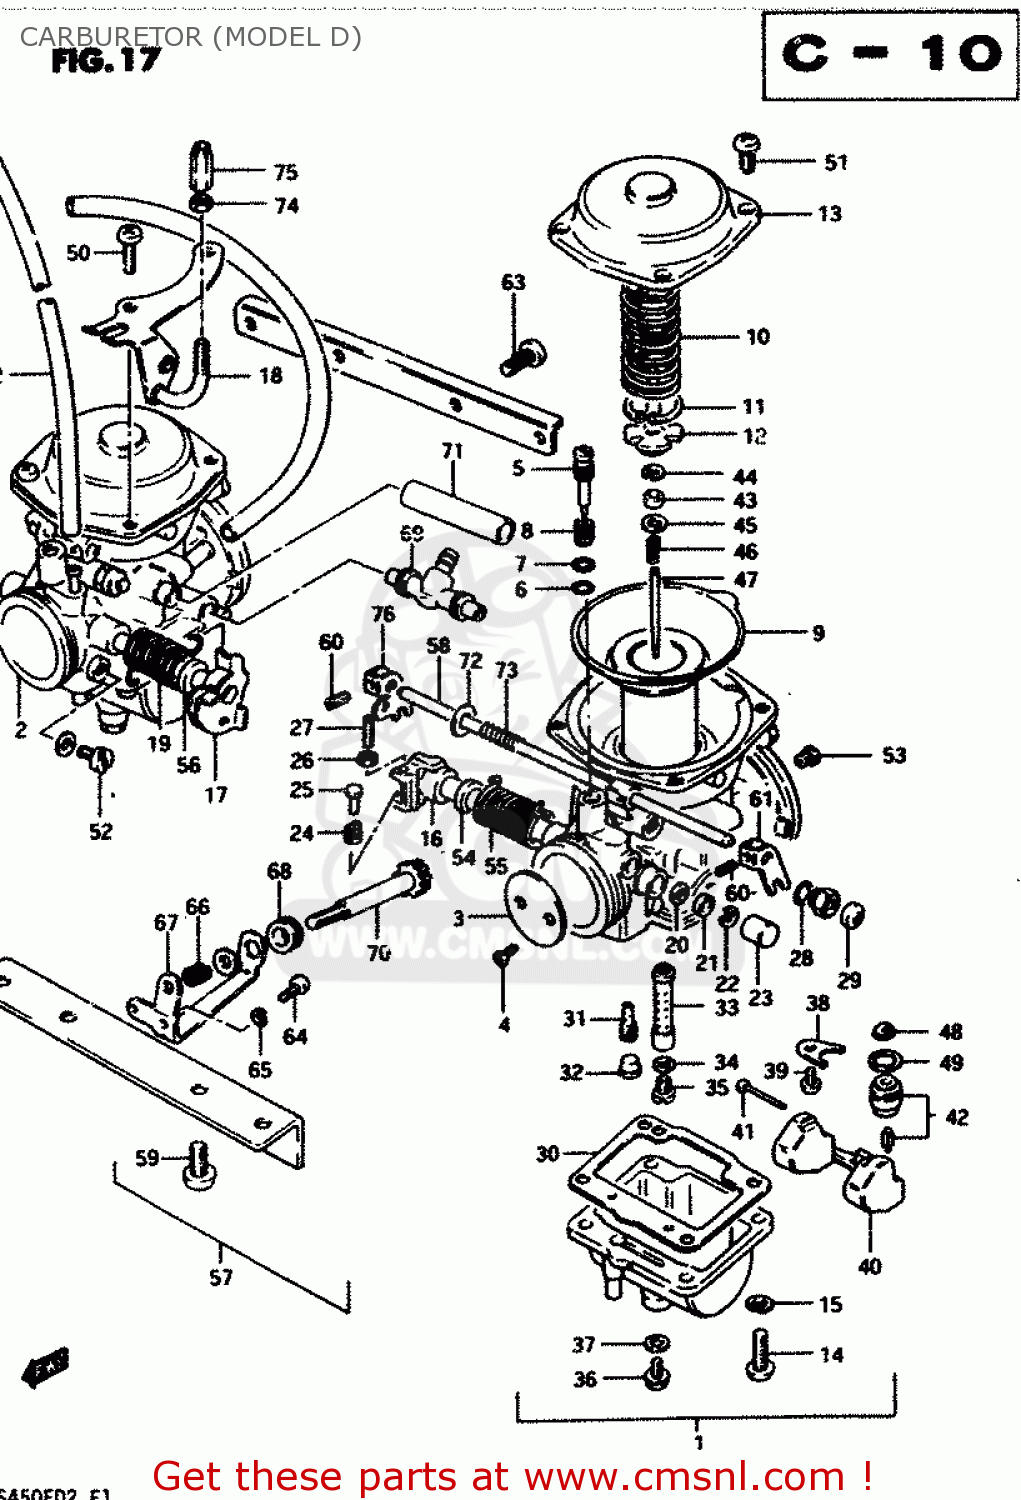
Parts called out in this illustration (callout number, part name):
1	CARBURETOR ASSY, LH
2	CARBURETOR ASSY, RH
3	VALVE, THROTTLE
4	SCREW
5	SCREW,PILOT AIR
6	O-RING
7	GASKET
8	SPRING
9	DIAPHRAGM ASSY
10	SPRING
11	E RING
12	HOLDER,GUIDE
13	COVER
14	SCREW
15	LOCK WASHER
16	SHAFT ASSEMBLY
17	SHAFT,THROTTLE
18	BRACKET,THROTTLE CABLE
19	SPRING
20	SEAL
21	GASKET,THROTTLE SHAFT (NAS)
22	E RING
23	CAP
24	SPRING,THROTTLE SCREW
25	PIN,THROTTLE LEVER
26	NUT
27	SCREW
28	O RING
29	CAP,STARTER VALVE
30	GASKET,FLOAT CHAMBER (NAS)
31	JET,PILOT(45)
32	PLUG,NEEDLE JET
33	JET,NEEDLE(R-0)
34	WASHER,NEEDLE NOZZLE
35	JET
36	PLUG,DRAIN
37	GASKET (NAS)
38	PLATE,NEEDLE VALVE FITING
39	SCREW 4X6
40	FLOAT
41	PIN,FLOAT
42	VALVE ASSEMBLY,NEEDLE
43	RING
44	CLIP
45	WASHER,JET NEEDLE
46	SPRING
47	NEEDLE, JET
48	FILTER
49	O-RING,NEEDLE VALVE
50	SCREW
51	SCREW
52	SCREW
53	JET,AIR(135)
54	SPACER,THROTTLE SHAFT
55	SPRING
56	SPACER,THROTTLE SHAFT
57	FLANGE ASSEMBLY,CARBURETOR
58	SHAFT,STARTER
59	SCREW 6X12
60	SCREW
61	LEVER
62	HOSE
63	SCREW
64	SCREW
65	LOCK WASHER
66	SPRING,THROTTLE ADJUST
67	BRACKET,THROTTLE ADJUST
68	CAP,RUBBER
69	NIPPLE,CARBURETOR
70	SCREW
71	HOSE
72	WASHER,STARTER PLUNGER
73	SPRING,STARTER
74	NUT
75	ADJUSTER
76	LEVER,STARTER
